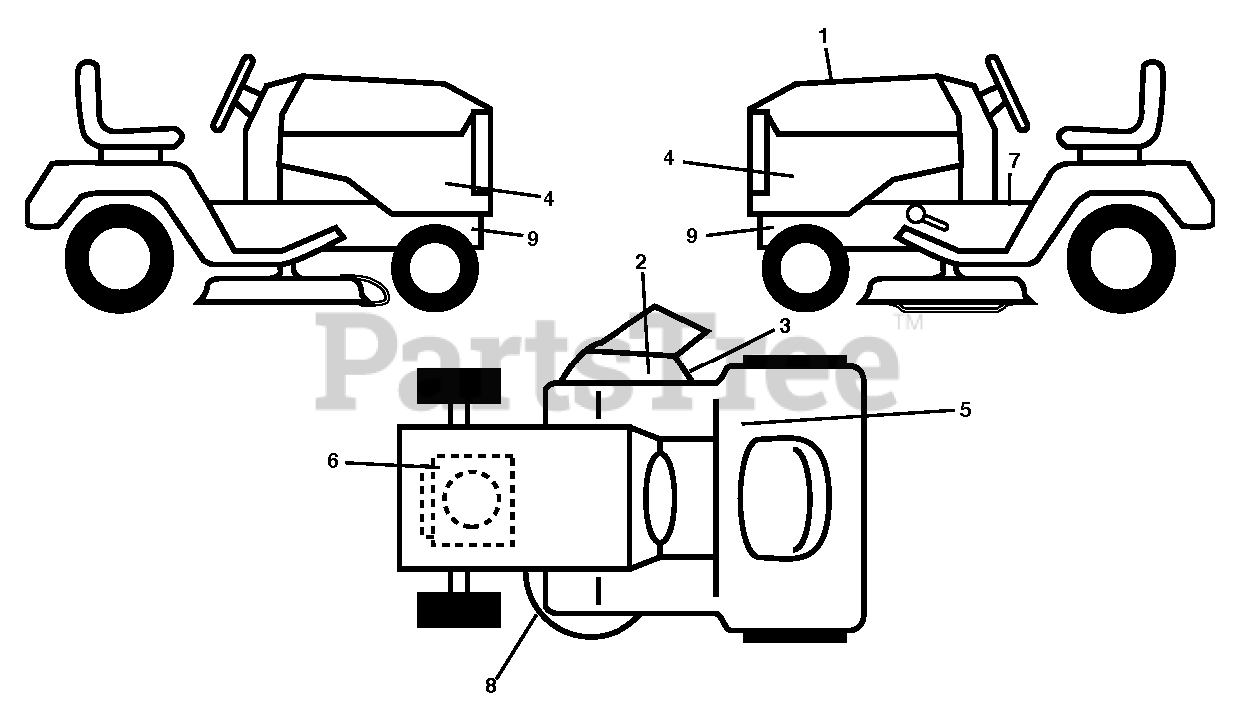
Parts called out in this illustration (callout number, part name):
2	DECAL, DECK DEFLECTOR, WARNING
2	DECAL.DECK.DEFLECTOR.WARNING
3	DECAL.DFLCTR.WARNNG.CTFNGR.SYM
6	DECAL.ENGINE.WARNING
7	DECAL.TRACTOR.SADDLE
8	DECAL.DECK.BELT.ROUTE.42"2021
8	DECAL.V-BELT.SCH.42/46"MEC/ELE
9	DECAL.WARNING.HOT.MUFFLER.2021
9	DECAL.CHASSIS.HOT.MUFFLER
